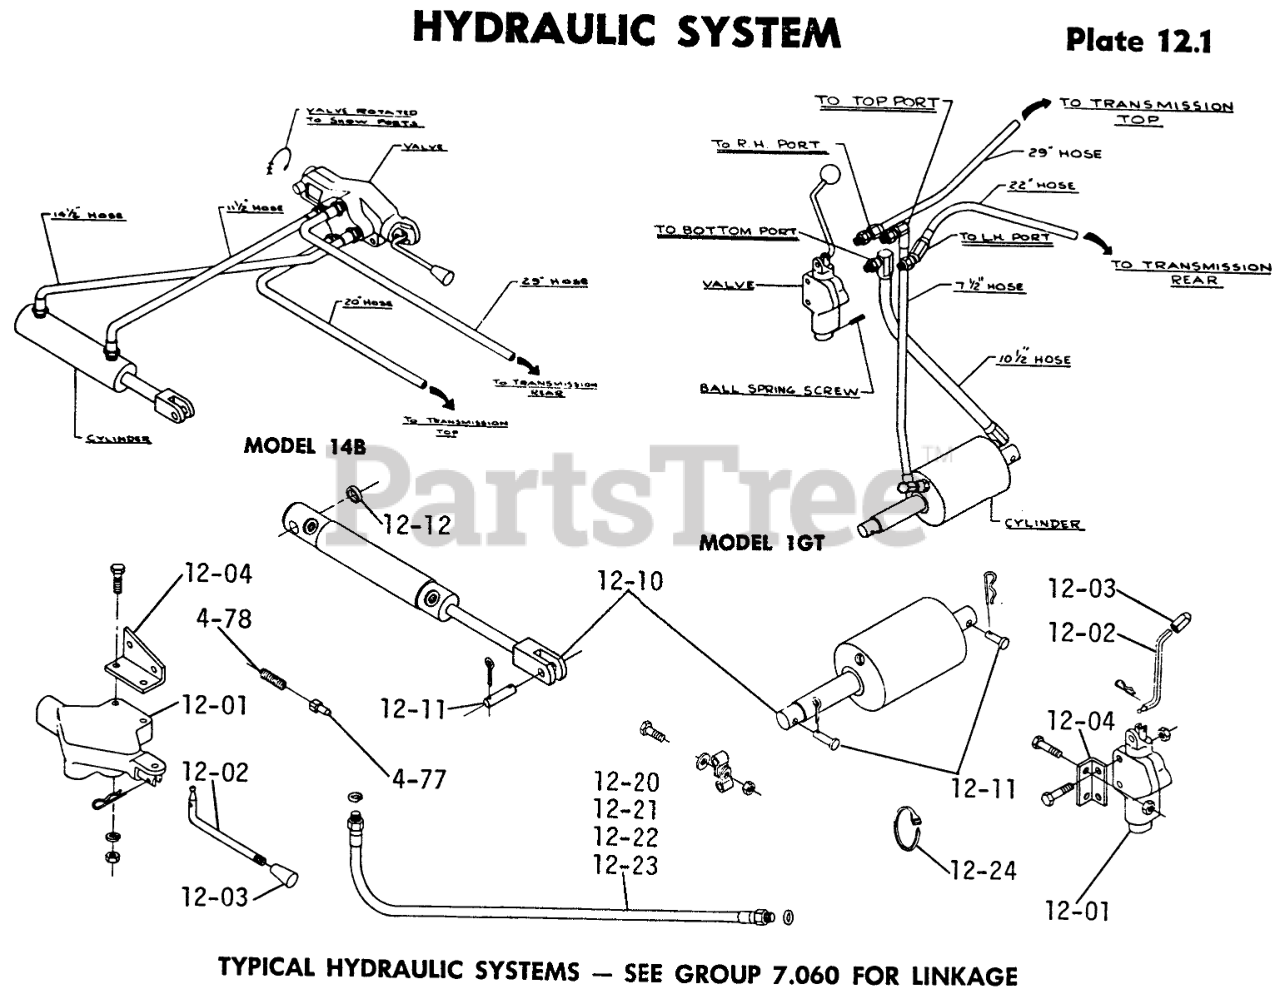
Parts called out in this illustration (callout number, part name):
12-01	Valve-Hydraulic
12-03	VALVE LEVER GRIP
12-03	Hairpin
12-04	Support Valve
12-04	Bolt-Carriage 5/16-18
12-04	Nut 5/16-18
12-04	Bolt 1/4 20 x 1 1/4
12-04	Nut-Nylok
12-11	Hairpin
12-11	Cotter Pin
12-21	HYD HOSE ASSY
12-23	O RING
12-23	Bolt 5/16-18 x 1
12-23	Nut 5/16-18
12-23	Washer
